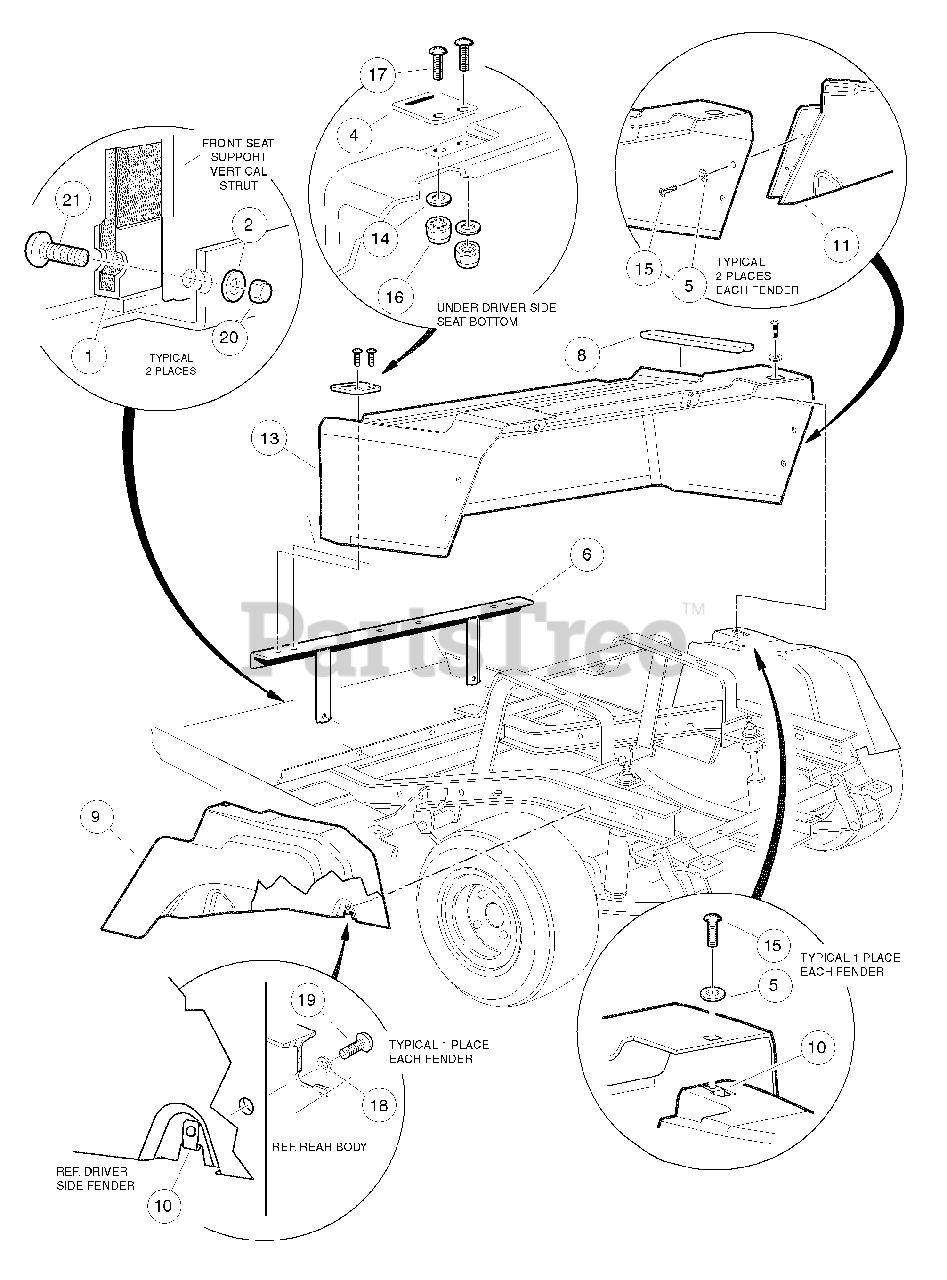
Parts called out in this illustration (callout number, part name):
1	Body Kick Plate
2	Washer, 1/4" Type B Flat
3	Body Asm, Electric, Orange
4	Body, Hinge Plate
5	Washer, 1/4" Type B Flat
6	Body Support Front
9	Fender, Driver Side
10	U-N ut, 1 /4-20 .
11	Fender, Passenger Side
12	U-N ut, 1 /4-20
13	Body, Rear, Electric, Orange
14	Washer, 1/4 Type A Narrow Flat
15	Screw, 1/4-20 X 0.75 Hex-Head Cap
16	Locknut, 1/4-20 Nylon Insert
17	Screw, 1/4-20 X 1.0 Truss-Head Machine
18	Washer, 1/4 Type A Narrow Flat
19	Screw, 1/4-20 X 0.75 Hex-Head Cap
20	Locknut, 1/4-20 Nylon Insert
21	Screw, 1/4-20 X 1.0 Truss-Head Machine
